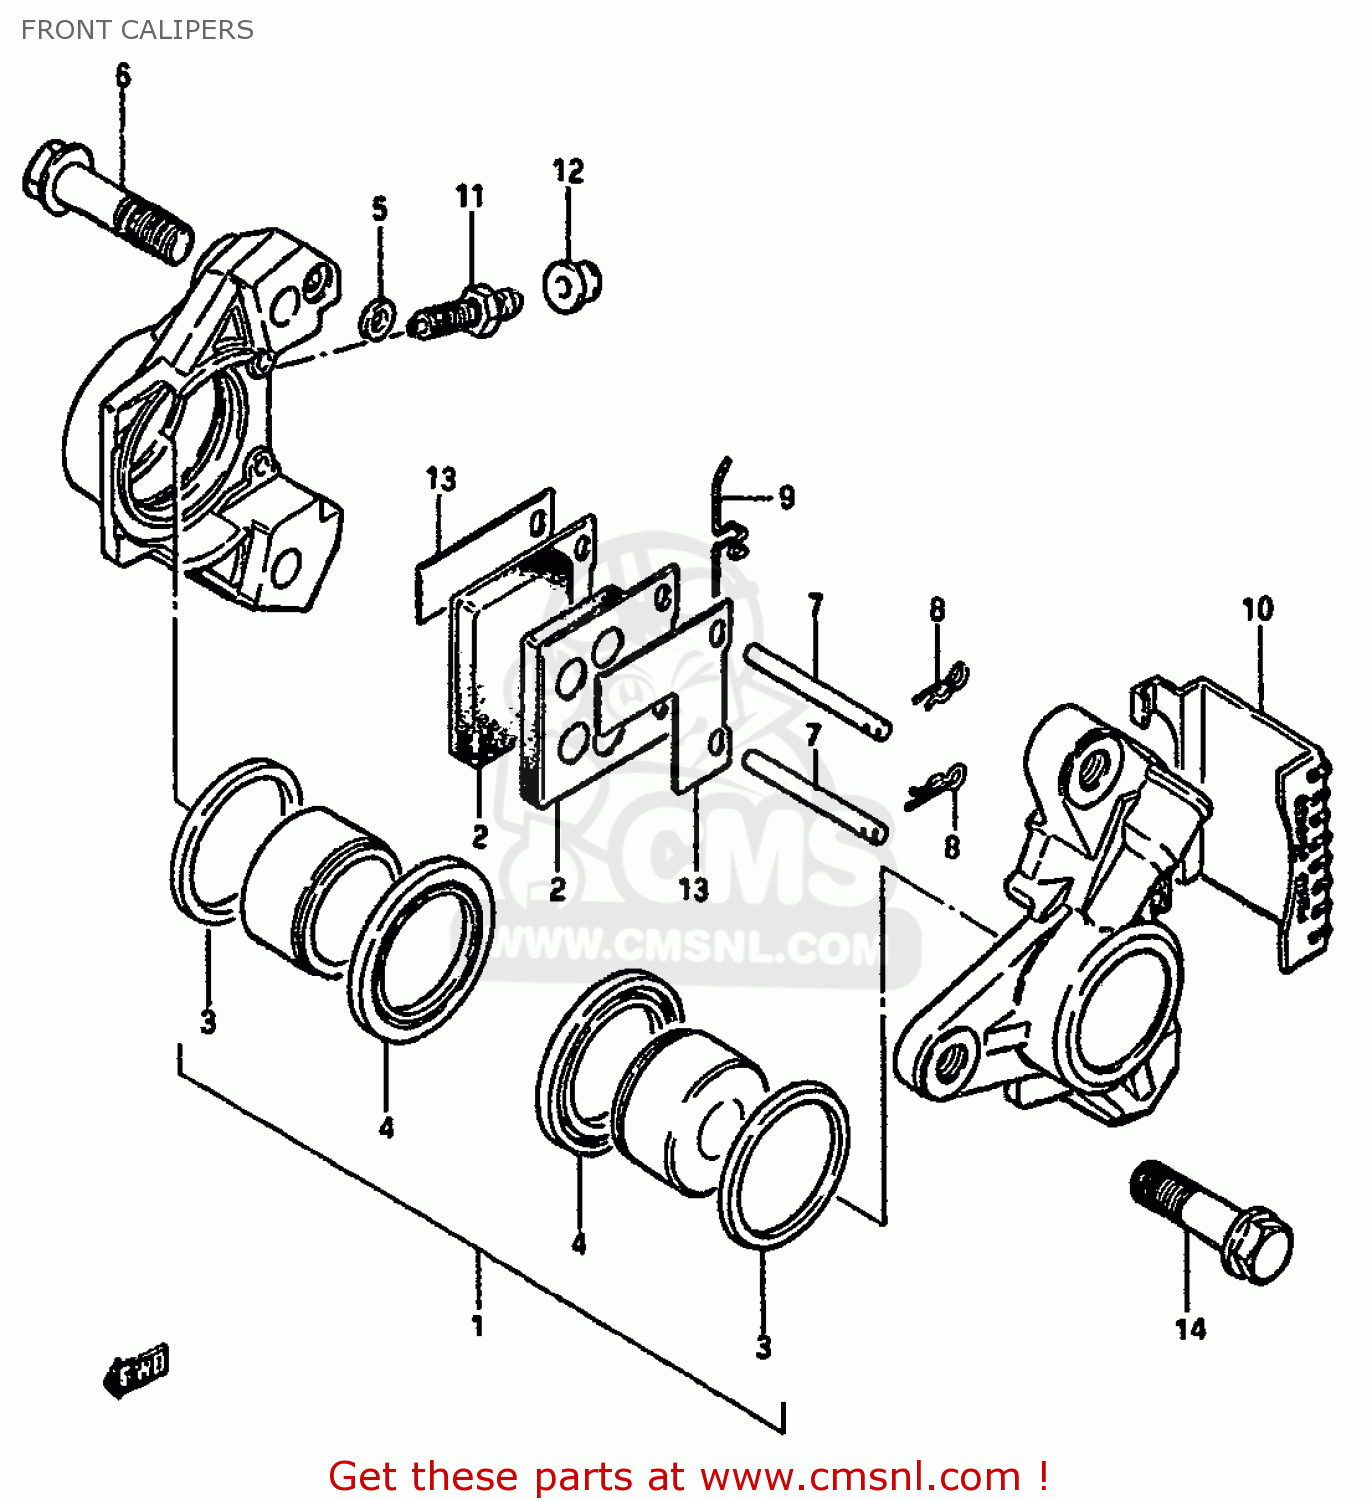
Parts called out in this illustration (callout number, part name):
1	PISTON SET
2	PAD
3	SEAL,PISTON
4	BOOT
5	SEAL,JOINT
6	BOLT,HOUSING
7	PIN,PAD
8	CLIP,PAD PIN
9	SPRING
10	COVER
11	BLEEDER
12	CAP,BREATHER
13	SHIM
14	BOLT 10X37
